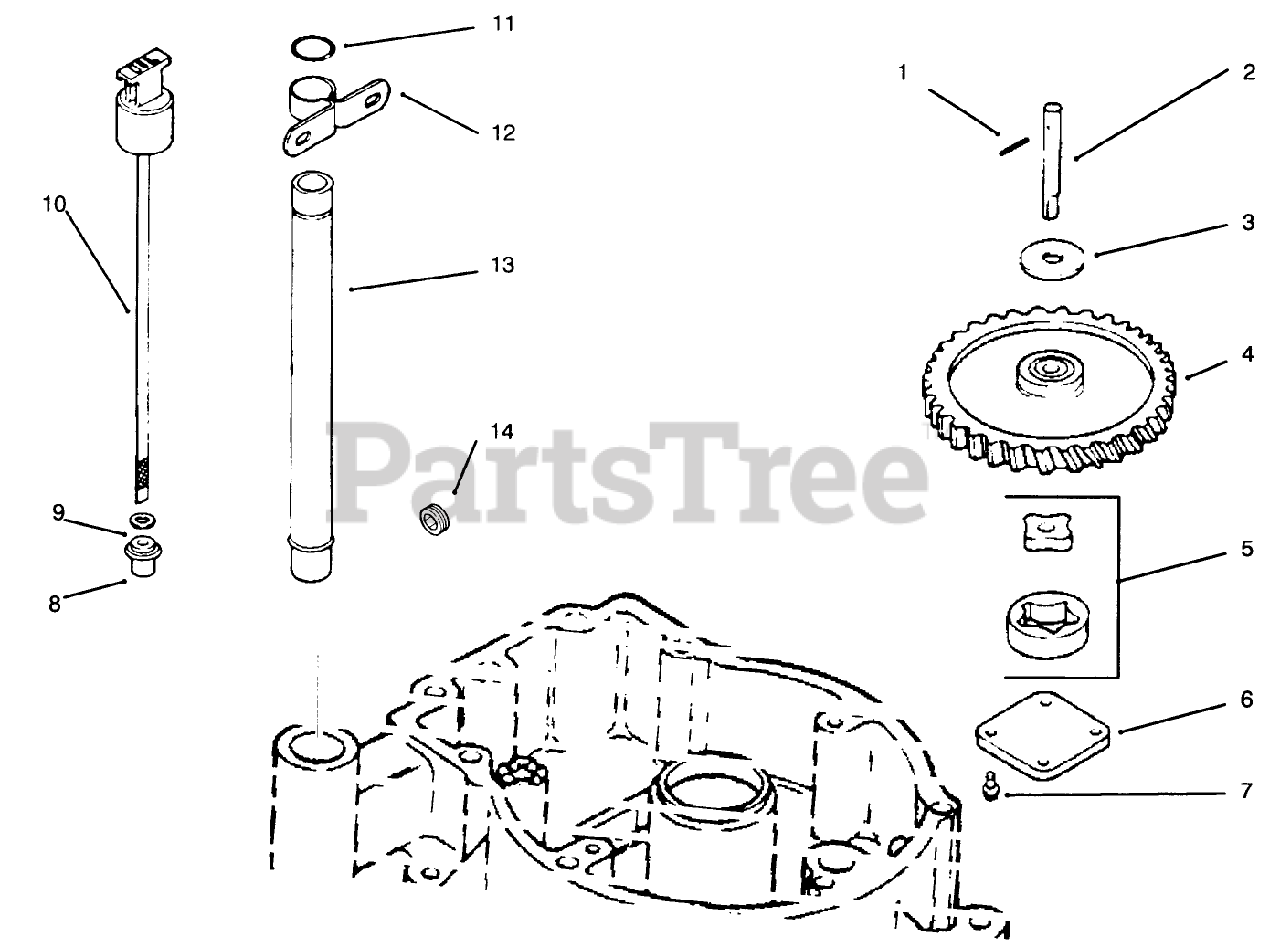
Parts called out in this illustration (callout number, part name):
1	Pin-Roll
2	Shaft-Oil Pump
3	Spacer-Shim
4	Gear-OiIPump
5	Rotor Set
6	Cover-Oil Pump
7	Screw-Hex. Washer Hd.
8	Seal-Rubber
9	Screw
10	Dipstick (Incl. Ref. #8-9)
11	O-Ring
12	Bracket-OilTubeSupport
13	Tube-Oil Fill
14	Plug-Countersunk Hex.
